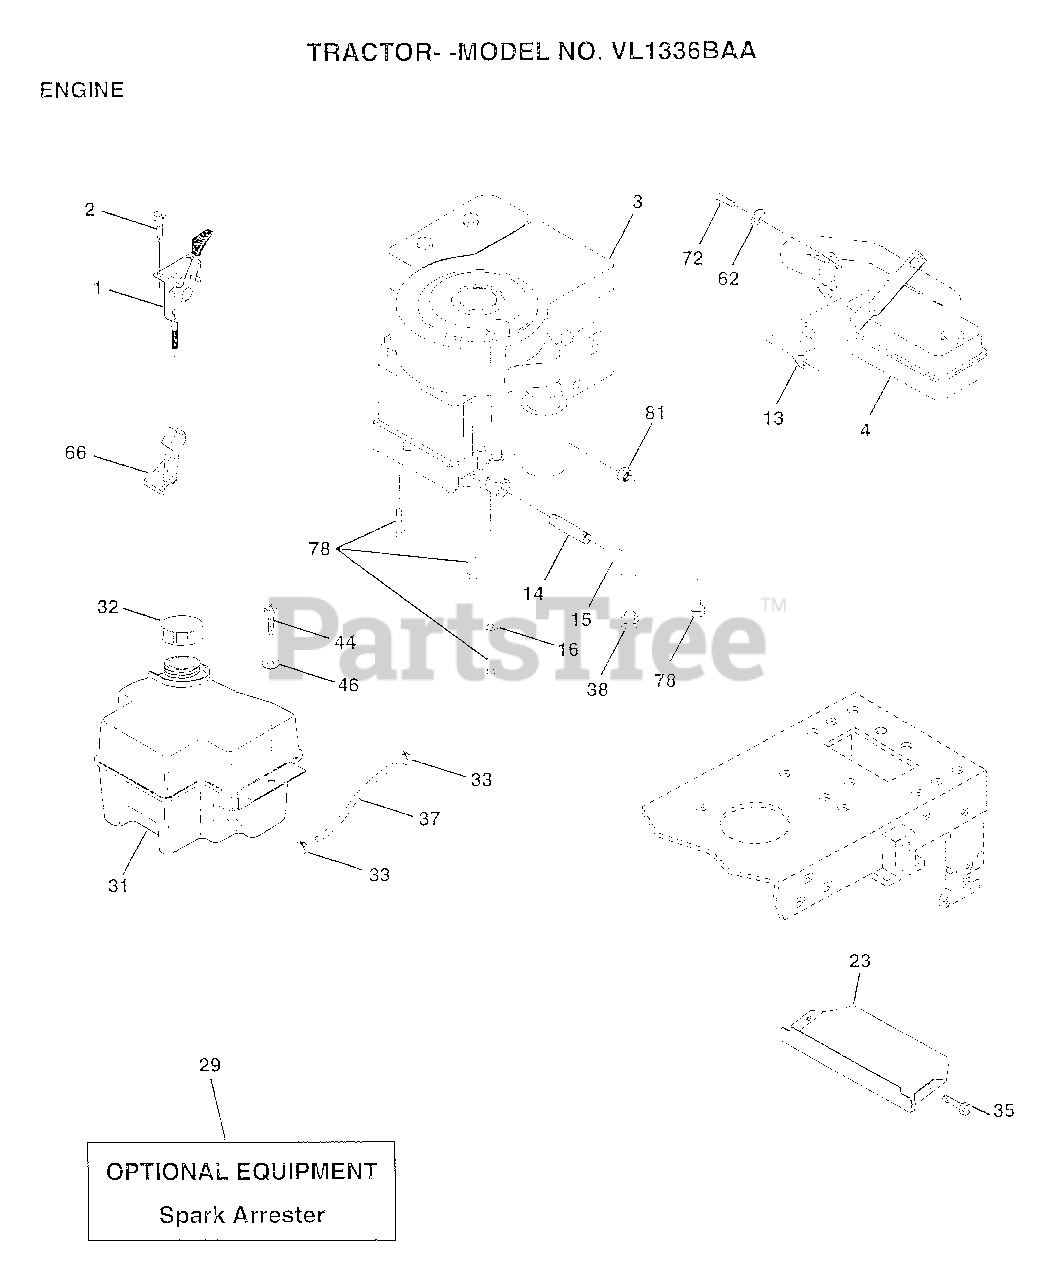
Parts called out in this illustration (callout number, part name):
1	CONTROL.THTL.23.5
2	SCREW LT
4	MUFFLER
14	PIPE NIPPLE
15	ELBOW
16	LOCKWASHER
23	SHIELD.BRN/DBR.GD
31	TANK.FUEL.FRONT.
32	CAP ASM FUEL
33	HOSE CLAMP
35	SCREW
37	LINE FUEL
44	SCREW HEX CRT
46	WASHER
62	LOCKWASHER
66	"STOP,DASH THROTT"
72	SCREW
78	SCREW
81	NUT
